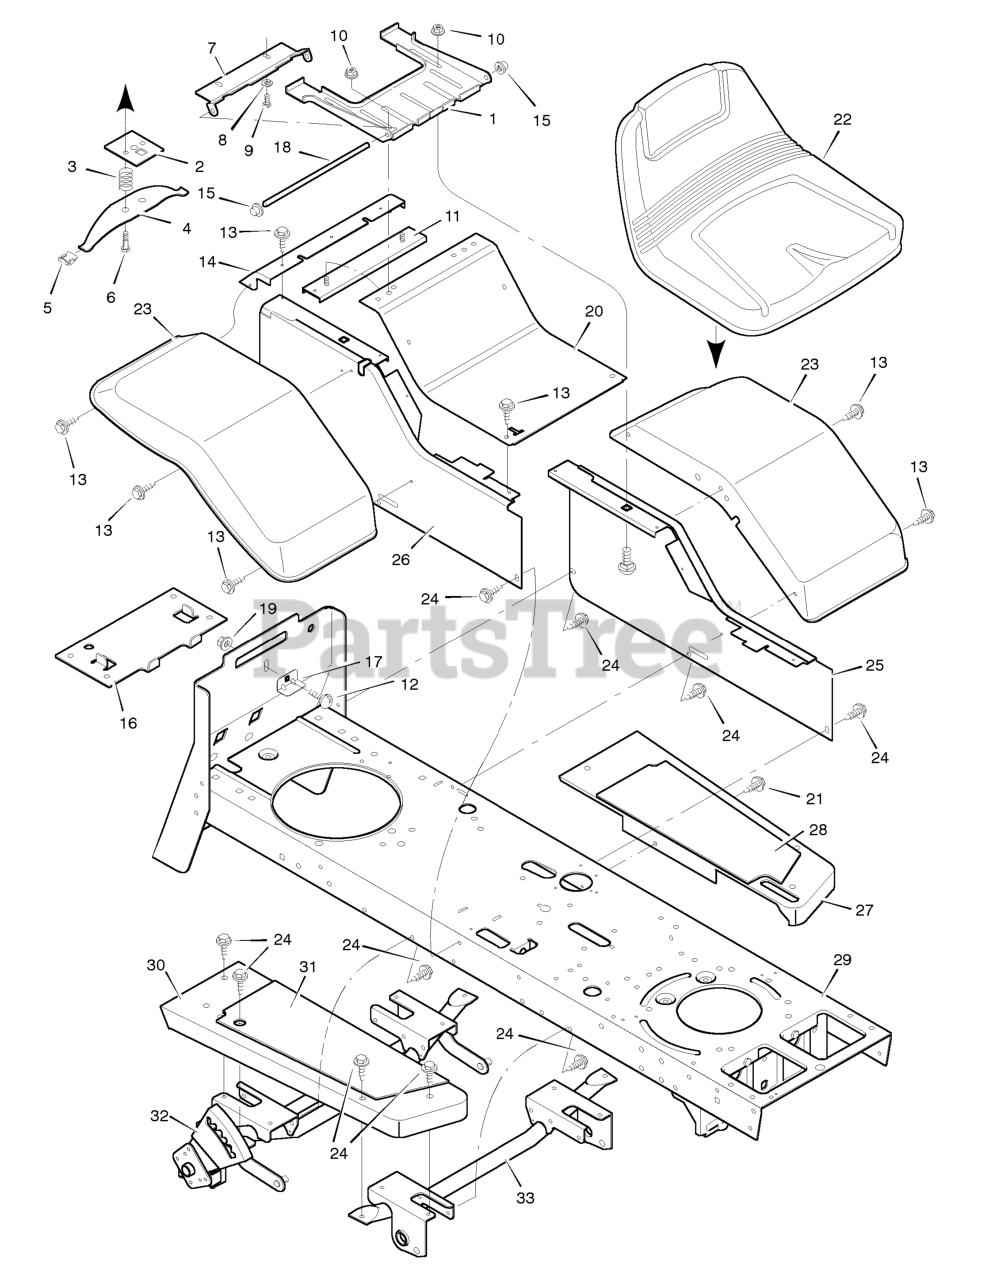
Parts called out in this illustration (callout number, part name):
1	Bracket, Seat
2	Plate Assembly, Switch
3	Spring, Compression
4	Spring, Seat
5	Glide, Spring
6	Bolt, Shoulder
7	Support, Seat
8	Lockwasher
9	Bolt, Hex
10	Locknut, Flange
11	Channel Assembly
12	Bolt, Carriage
14	Insert, Rear
15	Push On Cap
16	Support, Battery
17	Clamp, Battery
18	Rod, Pivot
19	Locknut
20	Panel, Top
21	Fastener, Panel
25	Panel, Left
26	Panel, Right
27	Running Board, Left
28	Mat, Left
29	Frame Channel
30	Running Board, Right
31	Mat, Right
32	Lifter and Support Assembly
33	Support Assembly, Front
